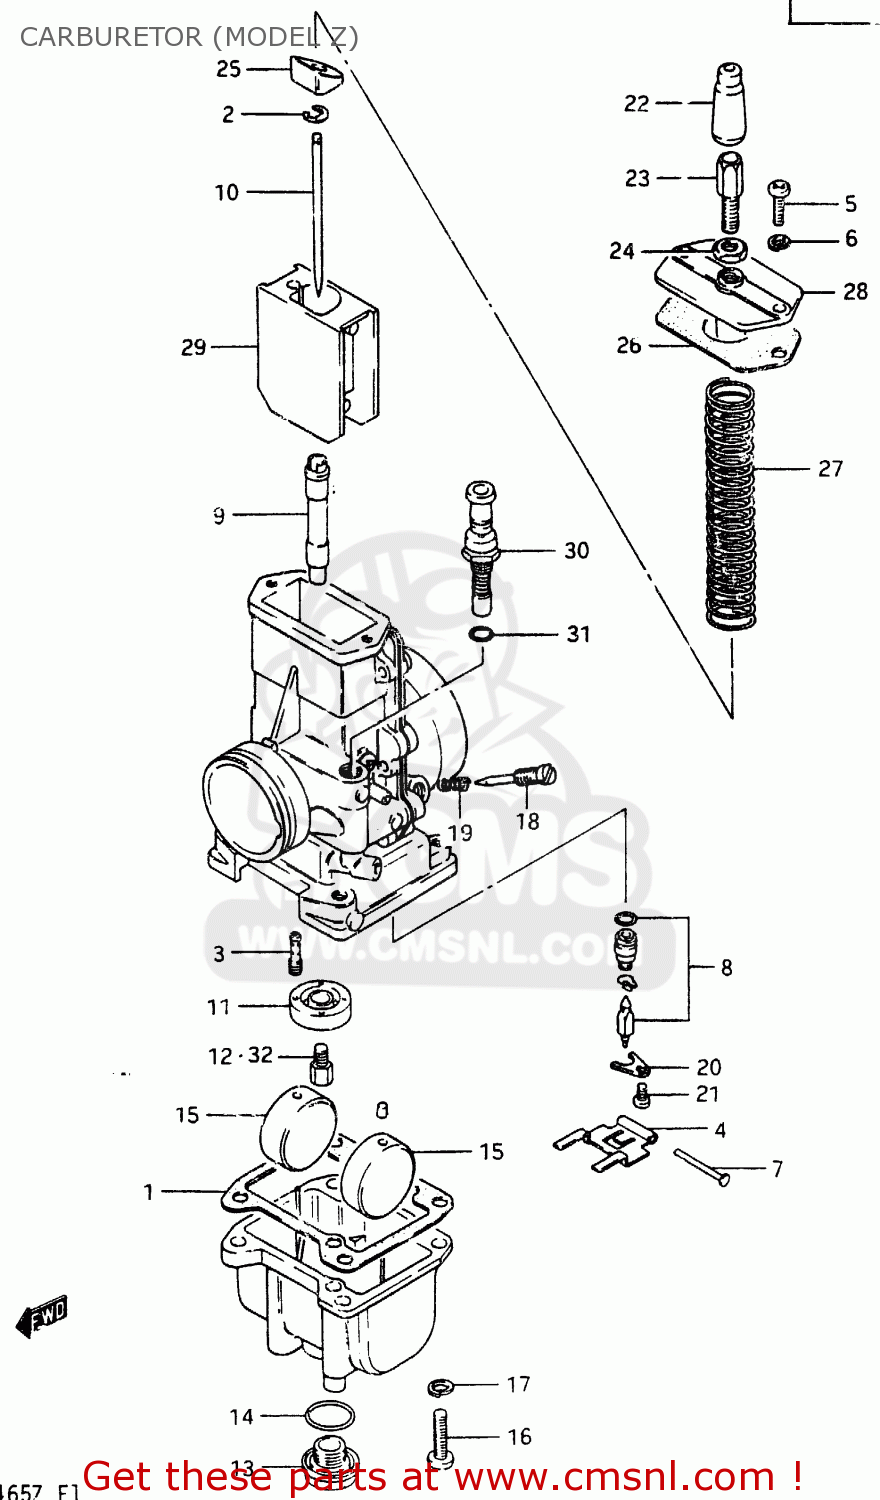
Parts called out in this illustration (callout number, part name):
1	GASKET,FLOAT CAHMBER (NAS)
2	CLIP
3	JET,PILOT(50)
4	ARM,FLOAT
5	SCREW
6	LOCK WASHER
7	PIN,FLOAT
8	VALVE ASSEMBLY,NEEDLE
9	JET,NEEDLE(R-0)
10	NEEDLE JET
11	RING,MAIN JET FIXING
12	JET
13	SCREW,GUIDE
14	O RING,DRAIN PLUG
15	FLOAT
16	SCREW 5X20
17	LOCK WASHER
18	SCREW,PILOT AIR
19	SPRING
20	PLATE
21	SCREW 4X6
22	CAP,CABLE ADJUSTER
23	ADJUSTER,CABLE
24	NUT
25	PLATE
26	SEAT,RETURN SPRING
27	GASKET,MIXING CHAMBER (NAS)
28	SPRING,THROTTLE VALVE
29	CAP,CARBURETOR,TOP
30	VALVE,THROTTLE
31	VALVE,STARTER
32	O-RING
33	JET
